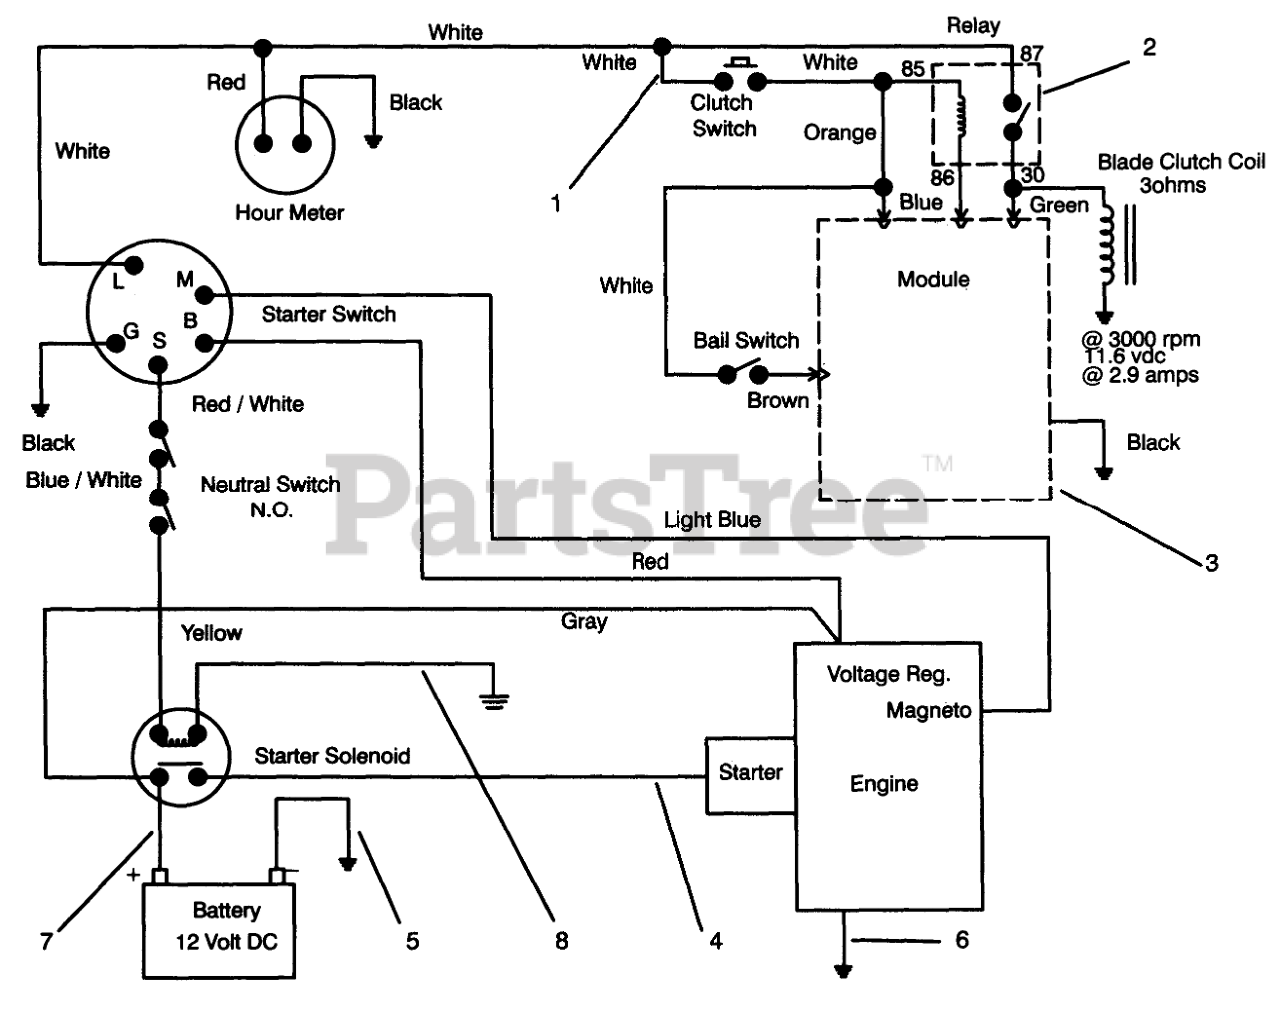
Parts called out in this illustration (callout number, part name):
1	WIRE HARNESS
2	RELAY
3	Module
4	WIRE-SOLENOID/STARTER
5	CABLE-BATTERY, NEGATIVE
6	WIRE ASM
7	WIRE ASM
8	WIRE ASSEMBLY
